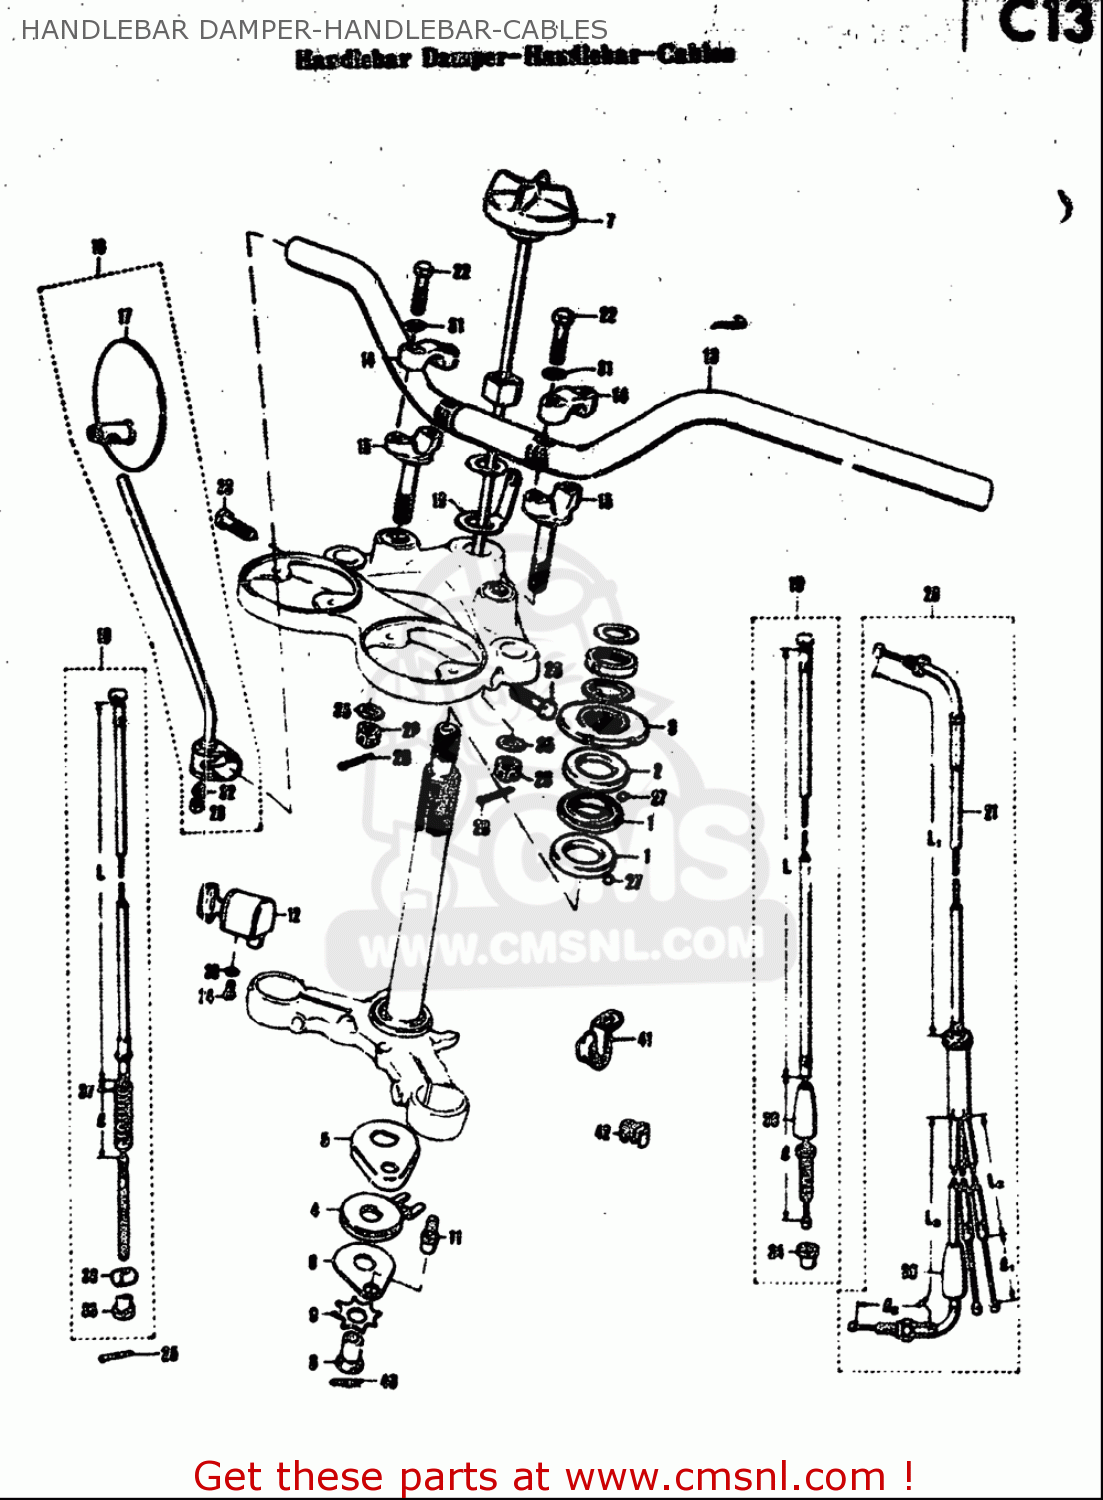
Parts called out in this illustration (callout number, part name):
3	NUT,STEERING STEM
6	SPACER,STEERING DAMPER
8	HUB,HANDLEBAR DAMPER S
9	SPRING, DAMPER ADJUST
10	STOPPER, DAMPER KNOB
11	BRACKET,STEERING DAMPER
14	HOLDER,HANDLEBAR
19	CABLE,CLUTCH
22	BOLT
23	BOLT
24	SCREW
27	BALL
28	NUT
29	NUT
30	WASHER,LOCK
31	WASHER,LOCK
32	WASHER
33	NUT
34	NUT
35	WASHER(10.5X30X2.3)
36	PIN(13X18)
37	SEAL,DUST
40	CLIP
42	CLIP
